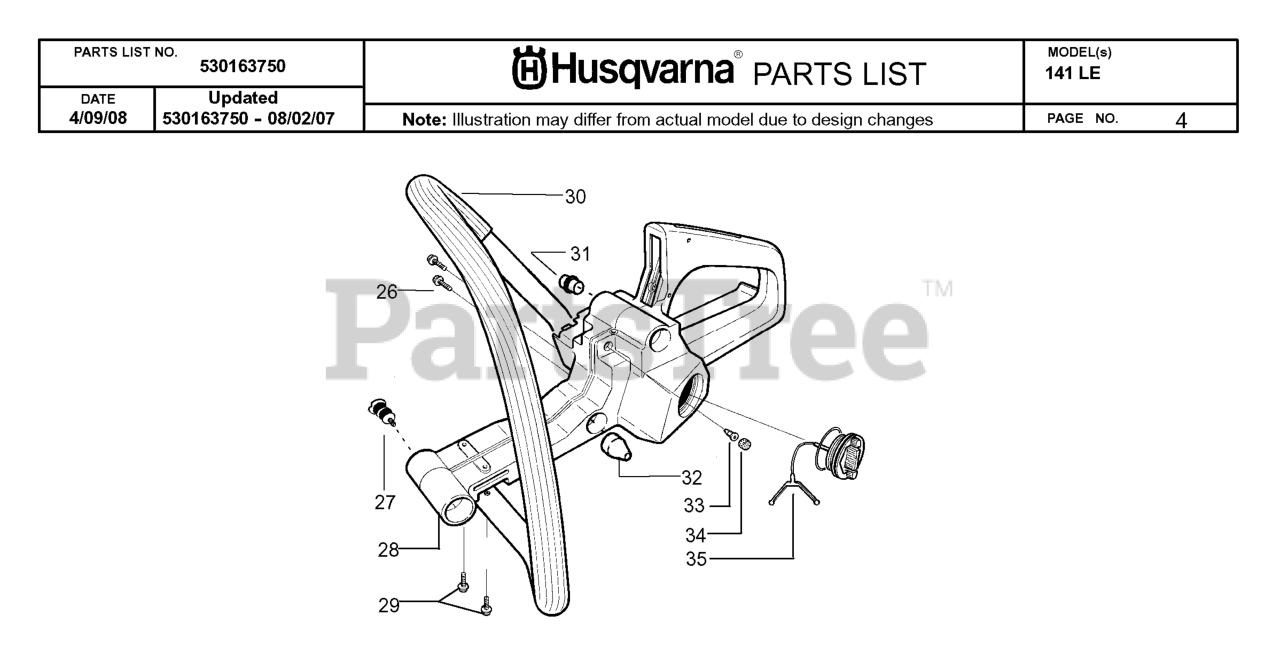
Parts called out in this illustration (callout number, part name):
1	STARTER HANDLE GRAY
5	PULLEY 36/41
6	RETURN SPRING
7	FAN HOUSING ASSEMBLY
8	SCREW,STRTR CVR 36/41
10	Decal - Fan Housing
11	LEAD WIRE ASSY
13	SWITCH ON/OFF
14	ROTOR COMPL. 36/41
15	WASHER-FLYWHEEL
18	%IGNITION MODULE
19	THROTTLE SHAFT 36/41
20	THROTTLE ACTUATOR 36/41
21	PIN,TRIGGER 36/41
22	TRIGGER SPRING 36/41
23	THROTTLE TRIGGER-KIT
24	HOSE. FUEL
25	FUEL PICK-UP
28	TANK HANDLE ASSY
30	FRONT HANDLE
31	FRONT HANDLE ISOLATOR
32	SHOCK MOUNT(X2) 36/41
33	VALVE-CHECK (DUCKBILL)
34	BRONZE PLUG
35	FUEL CAP KIT
